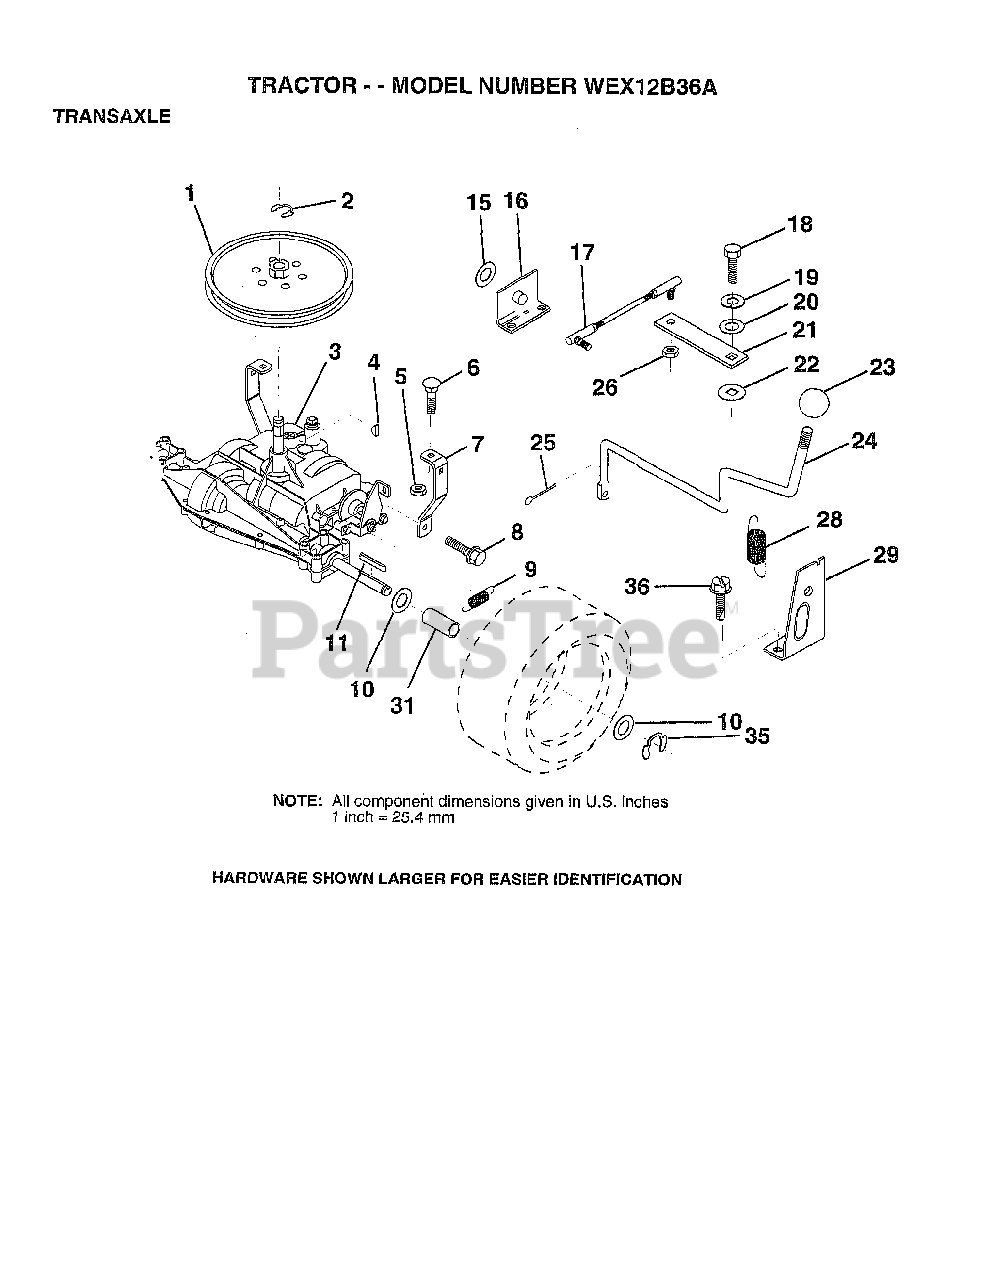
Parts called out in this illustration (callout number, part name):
1	PULLEY
6	BOLT
7	"STRAP,TORQUE"
8	SCREW
9	SPRING.BRAKE.RETU
10	WASHER
11	SQUARE KEY
16	"SUPT,HDLE SHT LH"
17	LINK SHIFT
18	BOLT.1/4-28.W/PAT
19	LOCKWASHER
20	WASHER LT
22	WASH-SHFT PLT LT
23	KNOB T (1/2-HOLE)
24	"ROD,SHIFT"
25	PIN COTTER 1/8
26	NUT.LOCK.5/16-24
28	"SPRING,EXT"
29	"SUPT,HDLE RH"
31	SPACER AXLE
32	WASHER
35	E-RING LT
36	SCREW
38	BOLT.HX.FLG.5/16
